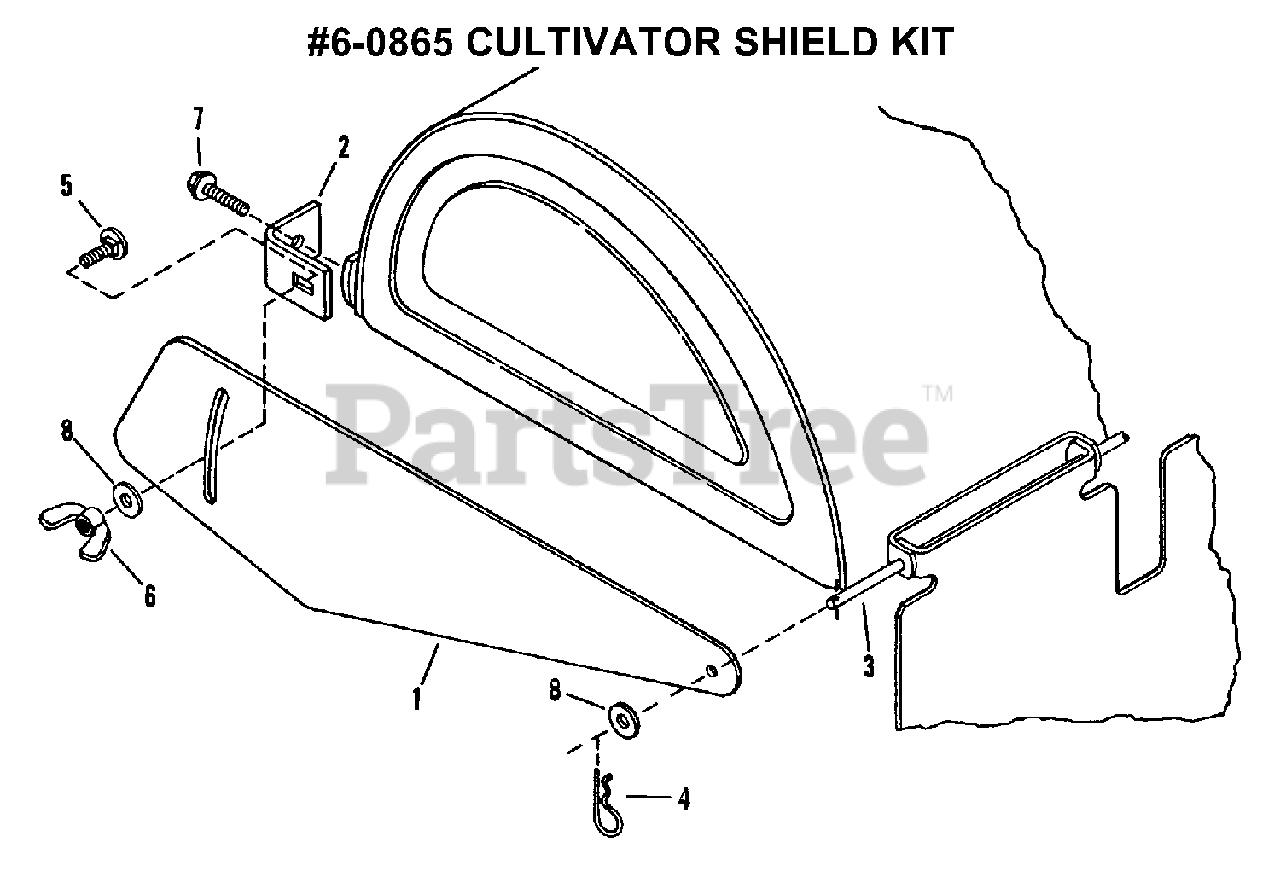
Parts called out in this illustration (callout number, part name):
1	CULTIVATOR, Shield
2	BRACKET, Front Latch
3	PIN, Drag Shield
4	PIN, 1/4" Hair
5	BOLT, 1/4-20 x 5/8" Flat Hd. Short Neck Carriage
6	SCREW, 1/4-20 x 1-1/4" Hex Washer Self-Tap
7	WASHER, 1/4" Flat
8	PIN, 3/32 x 3/4" Cotter
